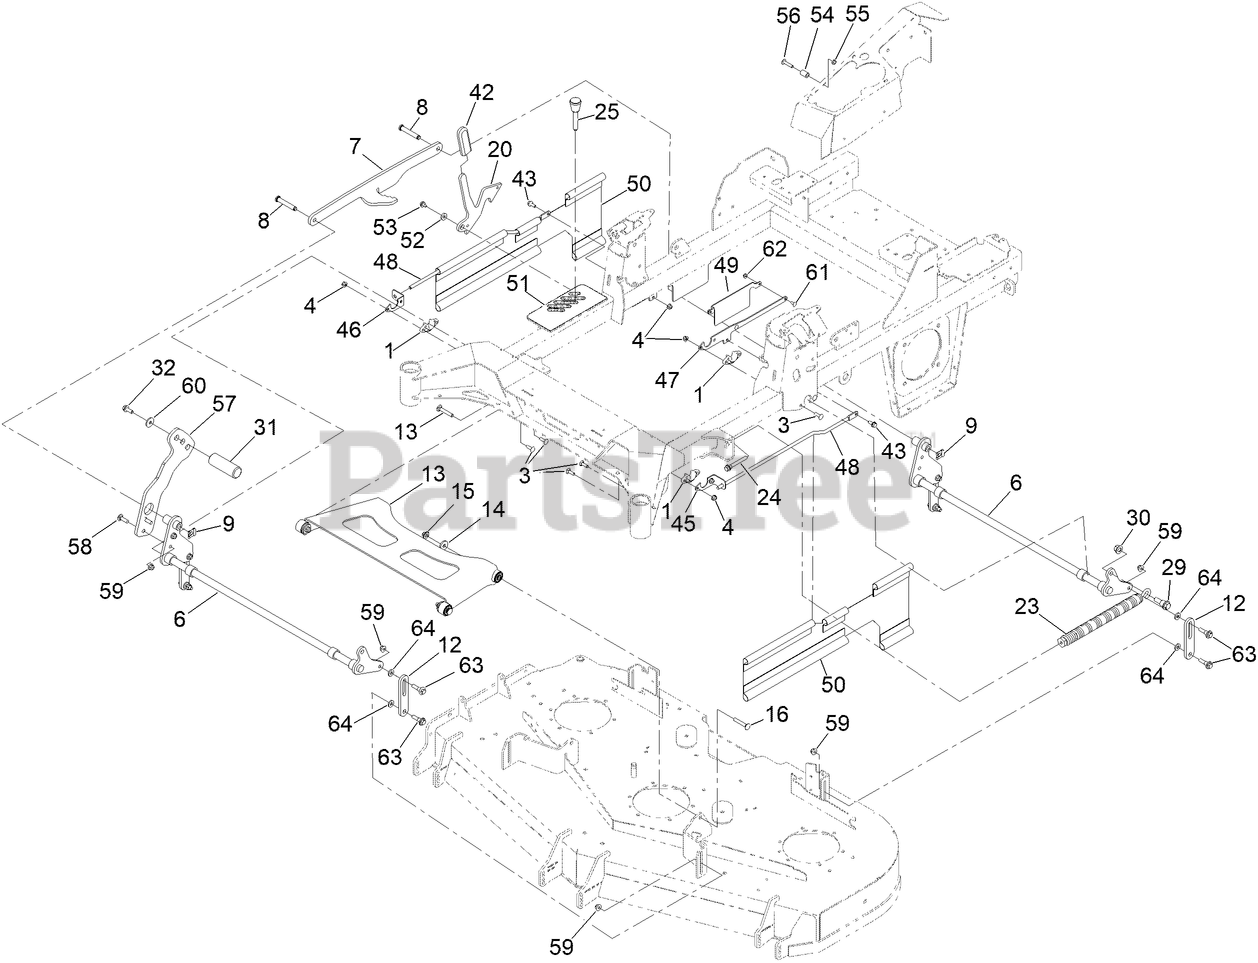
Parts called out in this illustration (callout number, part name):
1	BEARING-FLANGE
3	SCREW-CARR
4	NUT-HF, NI
6	DECK LIFT SHAFT ASM [BLACK]
7	LINK-LIFT
8	PIN-CLEVIS
9	CLIP-PIN
12	LINK-LIFT, DECK
13	ASM-DECK STRUT W/ BUSHINGS
14	WASHER
15	NUT-FLANGE, NI
16	SCREW-CARR
20	PLATE-TRANSPORT LOCK
23	SPRING-EXTENSION
24	BOLT-SHOULDER
25	PIN-HOC
29	SCREW-SHOULDER, HHF
30	NUT-LOCK
31	PEDAL-FOOT LIFT
32	SCREW-HHF
42	GRIP-LEVER
43	SCREW-HHF
45	BRACKET-MOUNT, UPPER FRONT (LH)
46	BRACKET-MOUNT, UPPER FRONT (RH)
47	BRACKET-MOUNTING, UPPER
48	ROD-SUPPORT, UPPER
49	BRACKET-FLAG
50	GUARD-SIDE
51	DECAL-HOC, MM
52	SPACER
53	SCREW
54	SPACER
55	NUT-LOCK, NI
56	SCREW-TORX
57	ARM-DECK LIFT [BLACK]
58	BOLT-CARR
59	NUT-HF, NI
60	WASHER
61	SCREW-CARR
62	NUT-HF
63	BOLT-SHOULDER
64	SPACER
